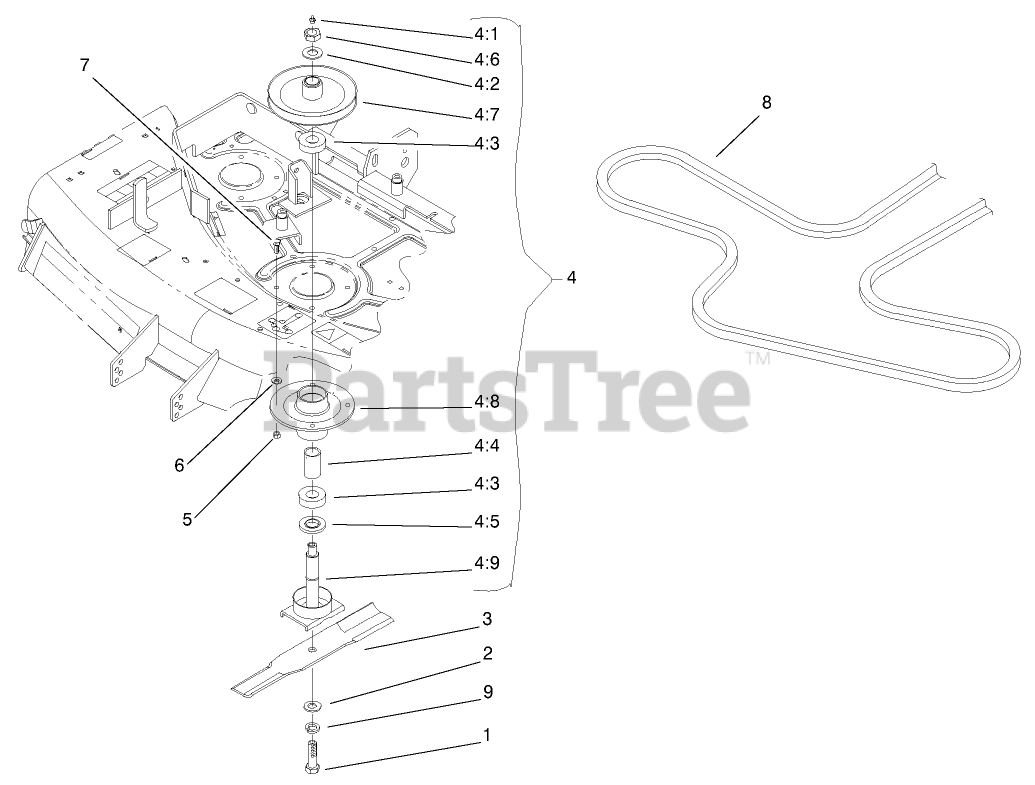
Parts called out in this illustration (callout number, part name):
1	SCREW-BLADE
2	WASHER-FLAT
3	Blade
4	SPINDLE HOUSING ASM
4:1	FITTING-GREASE
4:2	WASHER
4:3	BEARING-BALL
4:4	SPACER-BEARING
4:5	SPACER-SPINDLE
4:6	NUT-HEX
4:7	PULLEY AND HUB ASM
4:8	HOUSING-SPINDLE
4:9	Spindle Shaft ASM
5	NUT-LOCK, CONE
6	WASHER-FLAT
7	SCREW-HH
8	V-BELT, DRIVE
9	WASHER-LOCK
